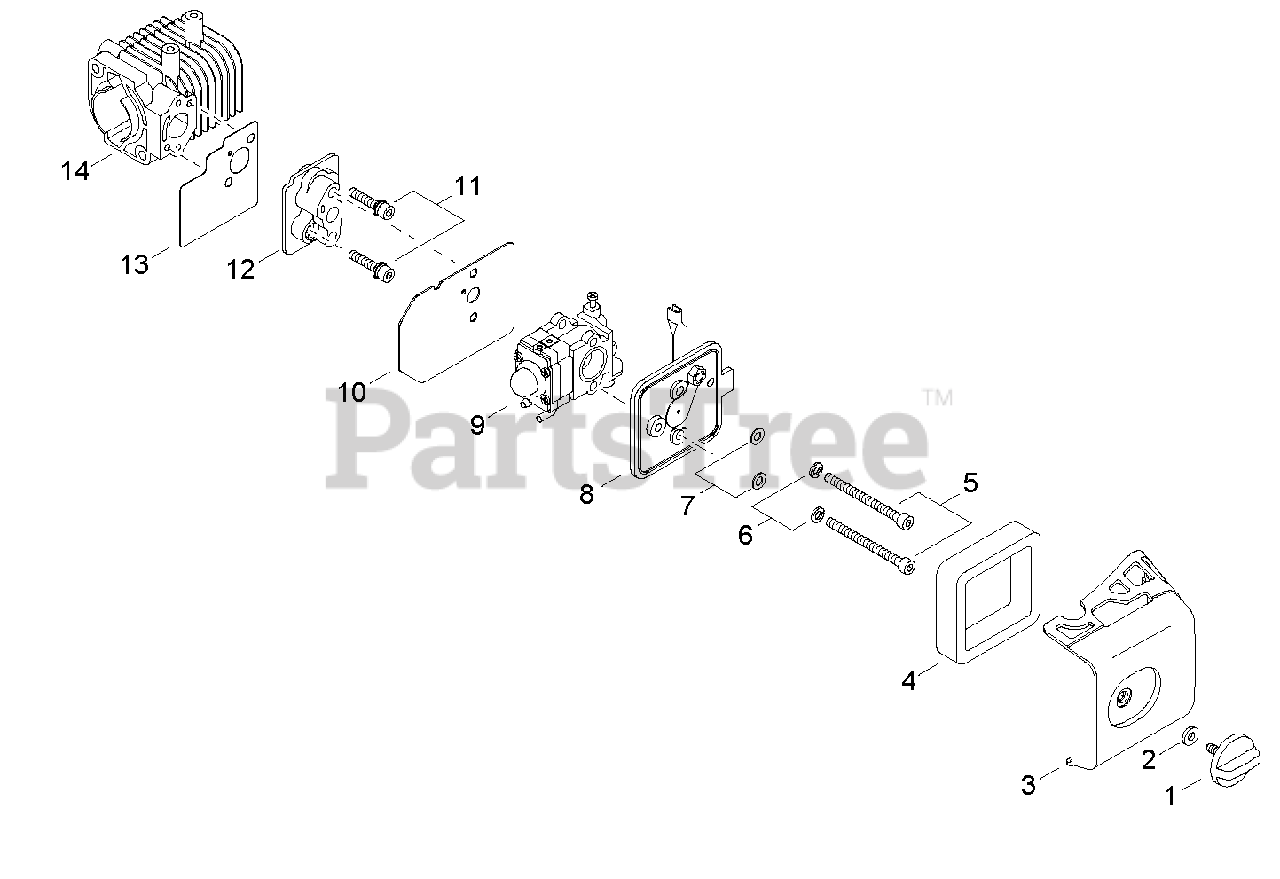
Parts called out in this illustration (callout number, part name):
1	THUMBSCREW
2	WASHER - VINYL
3	COVER, AIR FILTER
4	FILTER, AIR
5	SCREW - 5X55
6	LOCKWASHER - 5
7	WASHER - 5
8	AIR FILTER CASE ASSY
9	CARBURETOR WYJ-488
10	GASKET, INTAKE
11	SCREW - 5X30
12	INSULATOR, INTAKE
13	GASKET, INTAKE
14	CYLINDER
